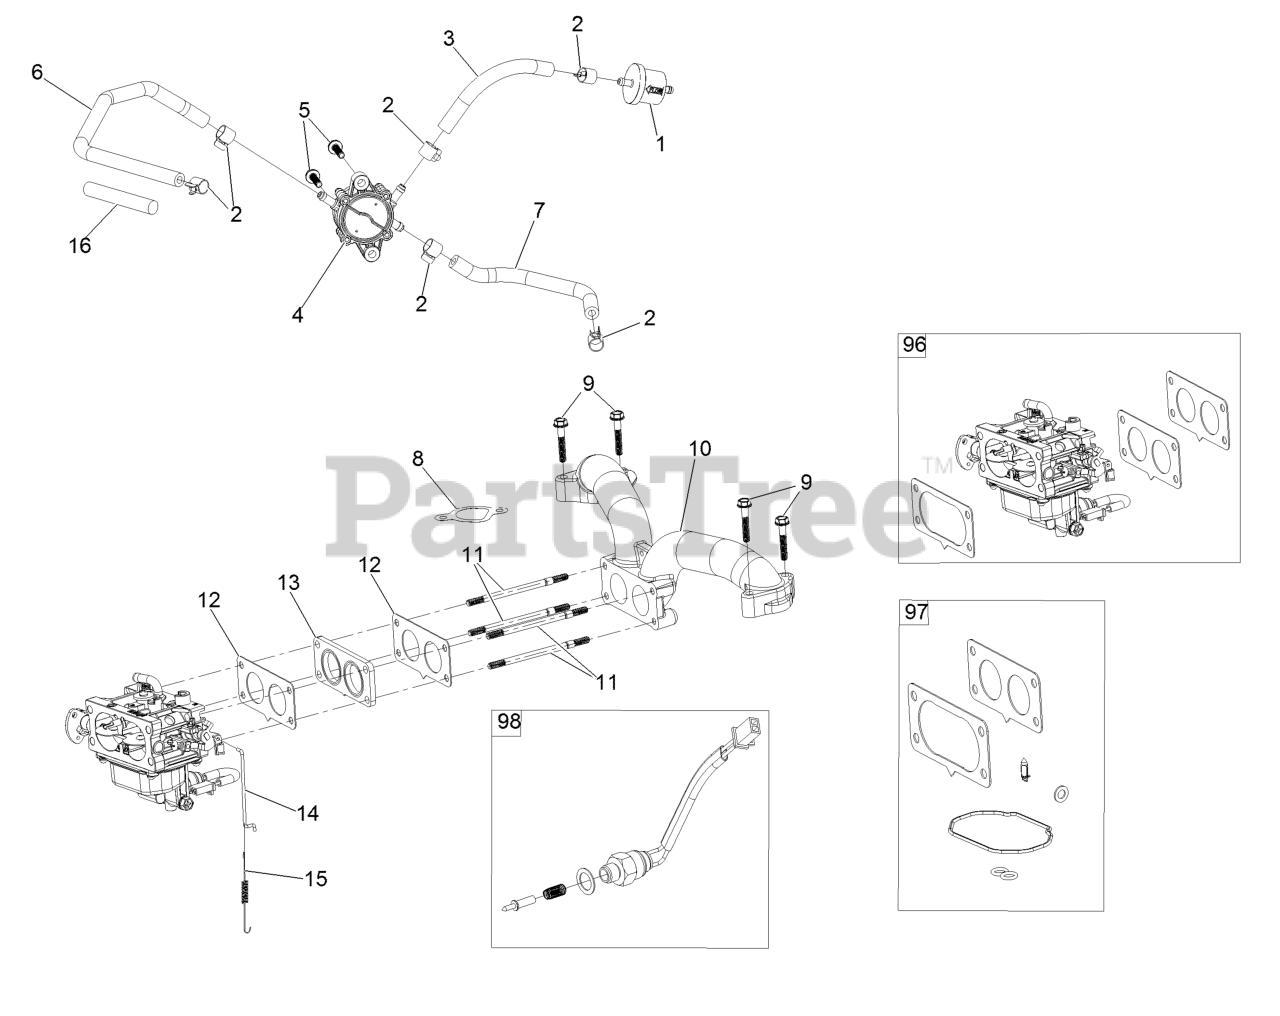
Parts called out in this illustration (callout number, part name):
1	Filter-Fuel
2	Clamp-Fuel Line
3	Line-Fuel
4	Pump-Fuel
5	Screw-HHF
6	Hose-Fuel
7	Hose-Fuel
8	Gasket-Intake
9	Screw-HHF
10	Manifold-Intake
12	Gasket-Carburetor
13	Insulator-Carburetor
14	Linkage-Throttle
15	Spring-Return, Throttle
16	Sleeve-Fuel Line Protector
96	Carburetor Replacement Kit
97	Carburetor Repair Kit
98	Solenoid Kit
99	High Altitude Kit
